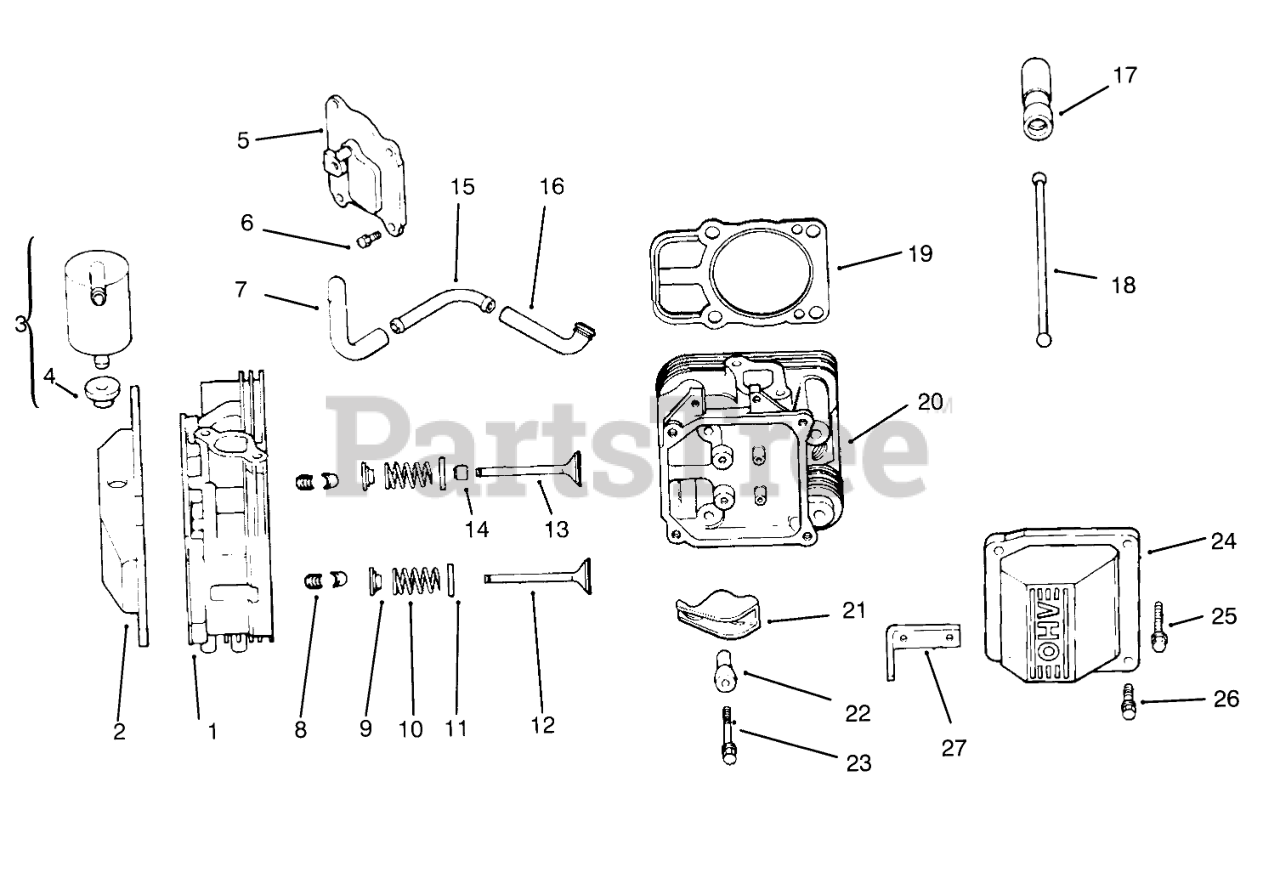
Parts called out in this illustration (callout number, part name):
1	Head ASM-#1 Cylinder (Only On: 72103)
2	Cover-Rocker (Only On: 72103)
3	Kit-Breather INCL 4 (Only On: 72103)
4	Grommet-Rubber (Only On: 72103)
5	Cover-Breather (Only On: 72103)
6	Screw M6x1.0x20 (Only On: 72103)
7	Hose-Breather (Only On: 72103)
8	Kit-Retainer (Only On: 72103)
9	Cap-Valve Spring (Only On: 72103)
10	Spring-Valve (Only On: 72103)
11	Retainer-Spring (Only On: 72103)
12	Valve-Exhaust (Only On: 72103)
13	Valve-Intake (Only On: 72103)
14	Seal-Valve Stem (Only On: 72103)
15	Fitting (Only On: 72103)
16	Hose-Breather (Only On: 72103)
17	Lifter-Valve (Only On: 72103)
18	Rod-Push (Only On: 72103)
19	Gasket-Cylinder Head (Only On: 72103)
20	Head ASM-#2 Cylinder (Only On: 72103)
21	Arm-Rocker (Only On: 72103)
22	Ball-Rocker Pivot (Only On: 72103)
23	Screw M6x1.0x34 (Only On: 72103)
24	Cover-Rocker (Only On: 72103)
25	Screw M10x1.5x91 (Only On: 72103)
26	Screw M6x1.0x30 (Only On: 72103)
27	Strap-Lifting (Only On: 721 03)
